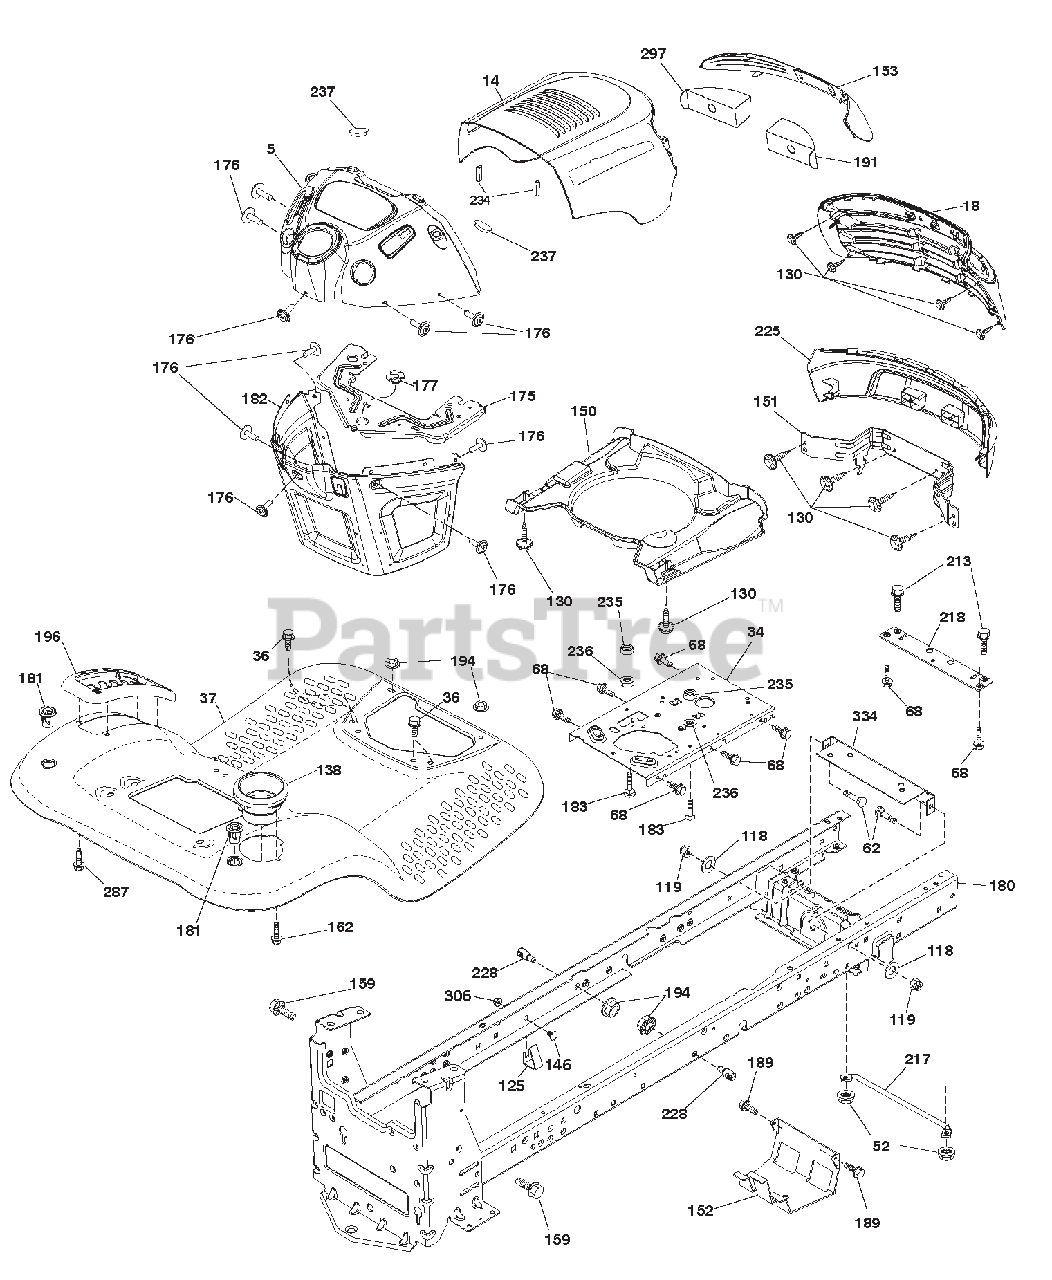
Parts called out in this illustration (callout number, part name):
18	GRILLE
34	PLATE.ENGINE.WELDED.CHASSIS
36	SCREW.5/16-18X3/4.SMGML.TAP/R
37	FENDER TLT W/CPH W/FW 422
52	Nut, Hex, Crownlock 5/16-18
62	Bolt 3/8-16 x 1 Gr. 5
68	SCREW.THDROL.5/16-18 X 1/2TYTT
118	WASHER.13/32 X 13/16 X 16 GA.
119	Nut, Hex, Crownlock 3/8-16
125	CLIP.FUEL.LINE
138	CUPHOLDER TL TEX 428
150	AIR DUCT.INTAKE.B&S
151	Bracket Pivot
152	SHIELD.BROWNING.W/TEX
153	LENS, ARIENS
159	SCREW.HEXWSH THDR3/8-16X3/4.BL
162	SCREW.HEX.WSH.HI-LO.1/4X1/2UNC
175	CROSSMEMBER.LT
176	SCREW.#10-24X5/8.RND.QUDRX.GIM
177	BUSHING.STEERING.LT
180	CHASS WLDMT TL 12 GA/2PC 18/22
181	BUSHING MNT FEND CRGO BLK TEX
182	DASH LOWER
183	BOLT.FIN.HEX.5/16-18 UNC X1-1/
189	SCREW.5/16-18X3/4.SMGML.TAP/BL
191	INSERT REFLECTIVE RH
194	Nut, Lock Hex Flange 5/16-18 u
196	CONSOLE ASSEMBLY
213	Bolt, Hex Head 5/16-18 x 3/4
217	ROD.PIVOT.HOOD
218	X-PIECE.HOOD.STOP.NON/STEALTH
225	BUMPER
228	STUD.FASTNER.W/'D'ANTI-ROTATIO
234	BUMPER HOOD
235	SPACER.FENDER
236	NUT.CENTER LOCK.5/16-18 UNC
237	PLUG.MOUNT.CARGO
287	SCREW.HEX.WASHEAD.1/4-20 X 3/8
297	INSERT REFLECTIVE LH
306	Nut, Hex, Flangelock 3/8-16
334	BRACKET ENGINE PLATE
